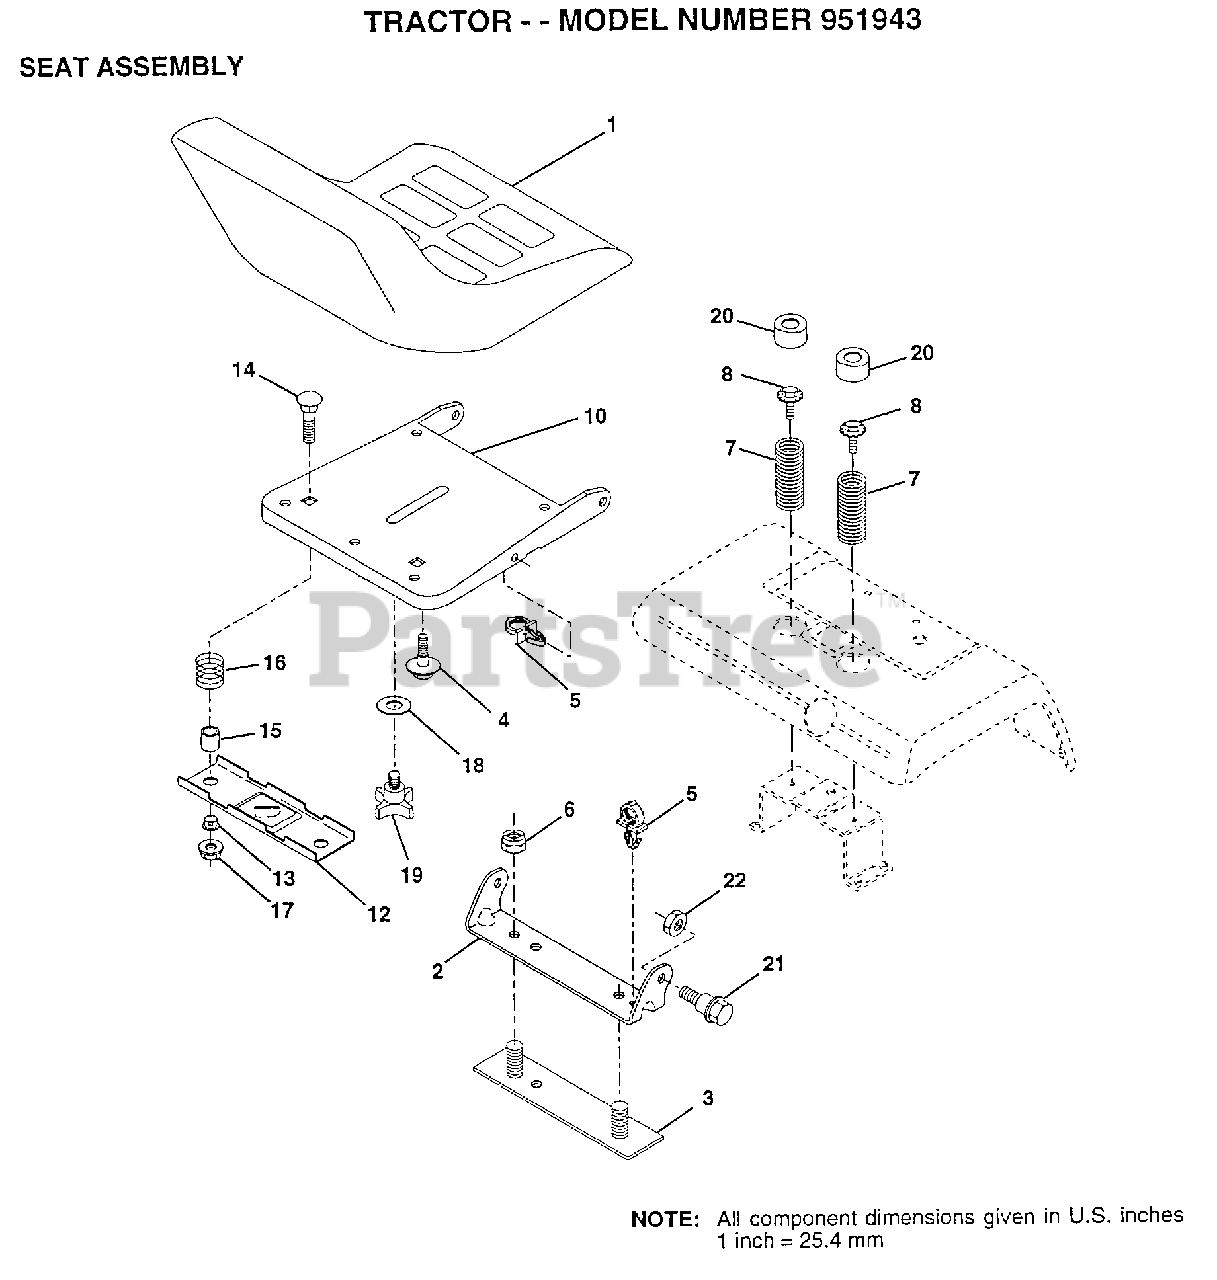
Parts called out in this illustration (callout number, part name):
2	BRACKET PVT SEAT
3	STRAP ASM FENDER
4	"BOLT,SHOULDER"
5	CLIP.PUSH-IN.HING
7	SPRING COMPRESSIO
8	BOLT.5/16-18.UNC
12	BRKT SWITCH
13	BUSHING
15	SPACER SPLIT
16	SPRING COMPRESSED
18	WASHER
19	"KNOB 1/2"" YT"
20	CAP SPRING
21	"BOLT,SHOULDER"
